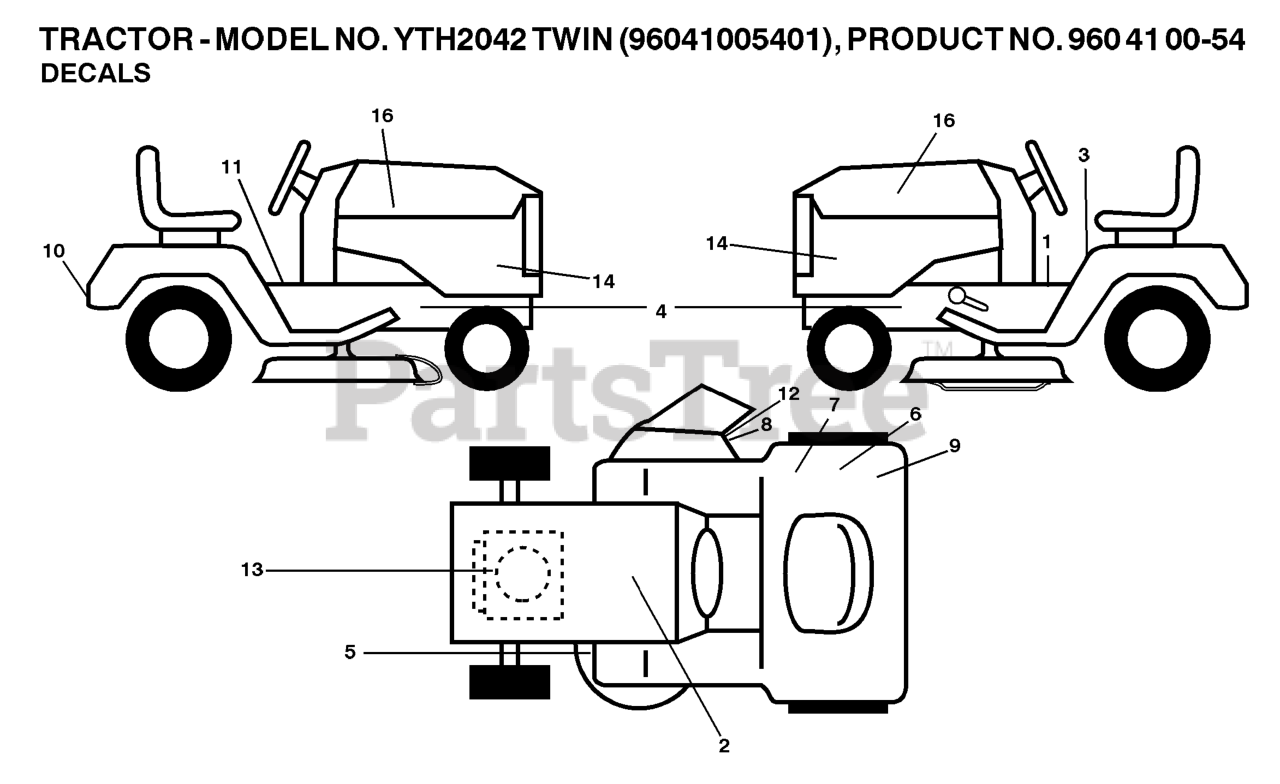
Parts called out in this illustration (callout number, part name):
1	DECAL PARK BRAKE
2	DECAL BTRY SYMBOLS
3	LABEL
5	DECAL V BELT SCHEMATIC
6	DECAL
7	DECAL 80 DBA
8	DECAL, DEFLECT WARNING
9	DECAL
10	DECAL
11	DECAL
12	DECAL.INTERNATIONL.CUTFINGER
13	DECAL
16	DECAL.HOOD.LOGO.ORANGE.HUSQVAR
